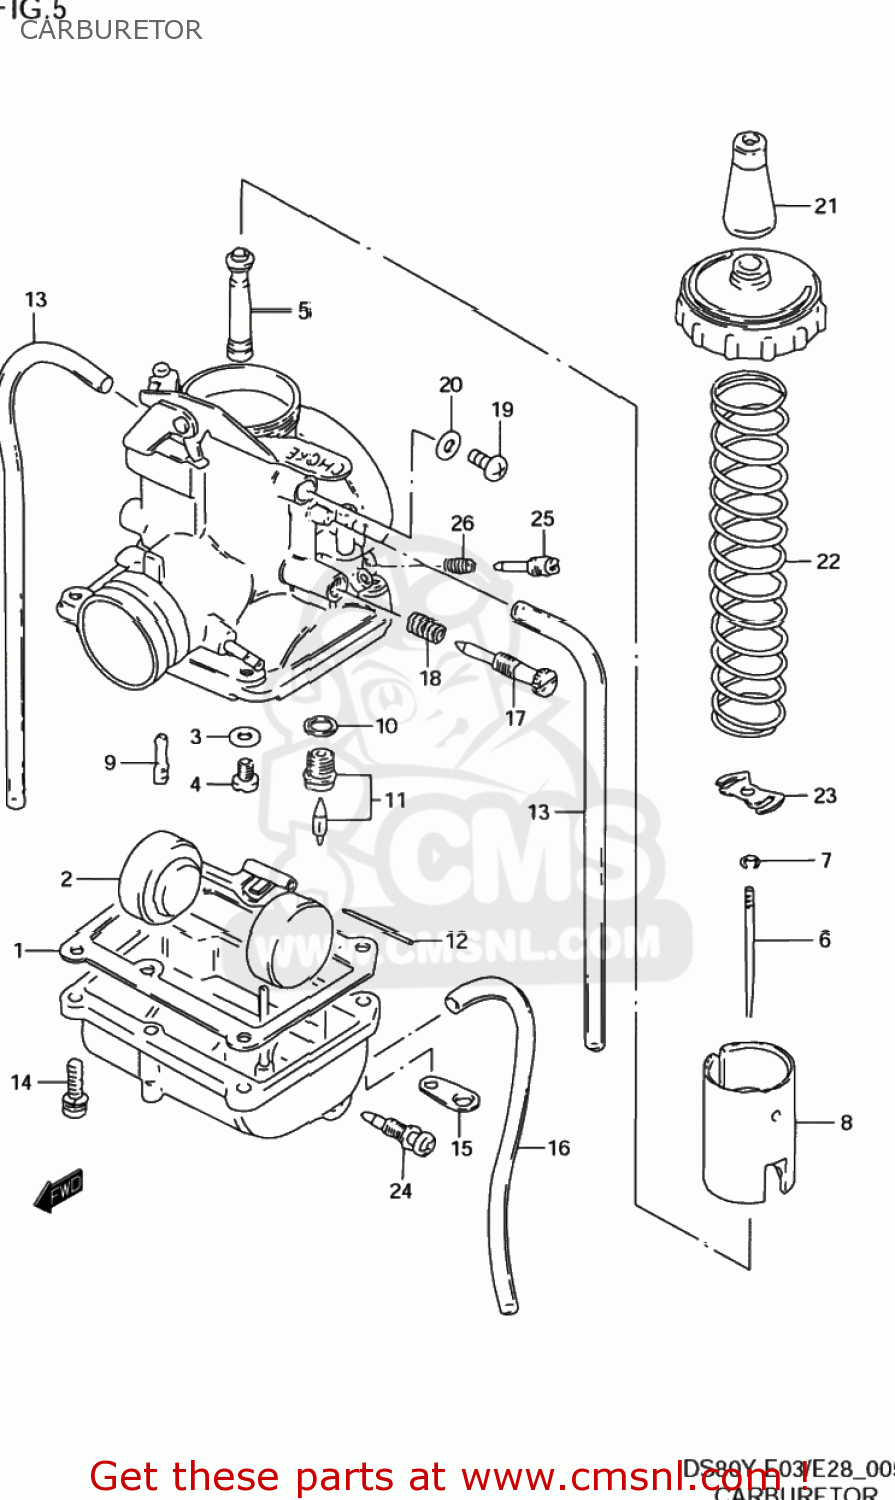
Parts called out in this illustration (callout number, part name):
1	GASKET,FLOAT CHAMBER (NAS)
2	FLOAT
3	WASHER
4	JET,MAIN(87.5)
5	JET,NEEDLE
6	NEEDLE,JET
7	CLIP
8	VALVE,THROTTLE
9	JET,PILOT(25)
10	GASKET,NEEDLE VALVE (NAS)
11	VALVE ASSY,NEEDLE
12	PIN,FLOAT
13	HOSE(3X5X600)
14	SCREW
15	PLATE
16	HOSE(3X5X650)
17	SCREW,THROTTLE STOP
18	SPRING,THROTTLE SCREW
19	SCREW
20	GASKET,DRAIN PLUG (NAS)
21	CAP,CABLE ADJUSTER
22	SPRING,THROTTLE VALVE
23	STOPPER,NEEDLE CLIP
24	PLUG,DRAIN
25	SCREW,PILOT AIR
26	SPRING
